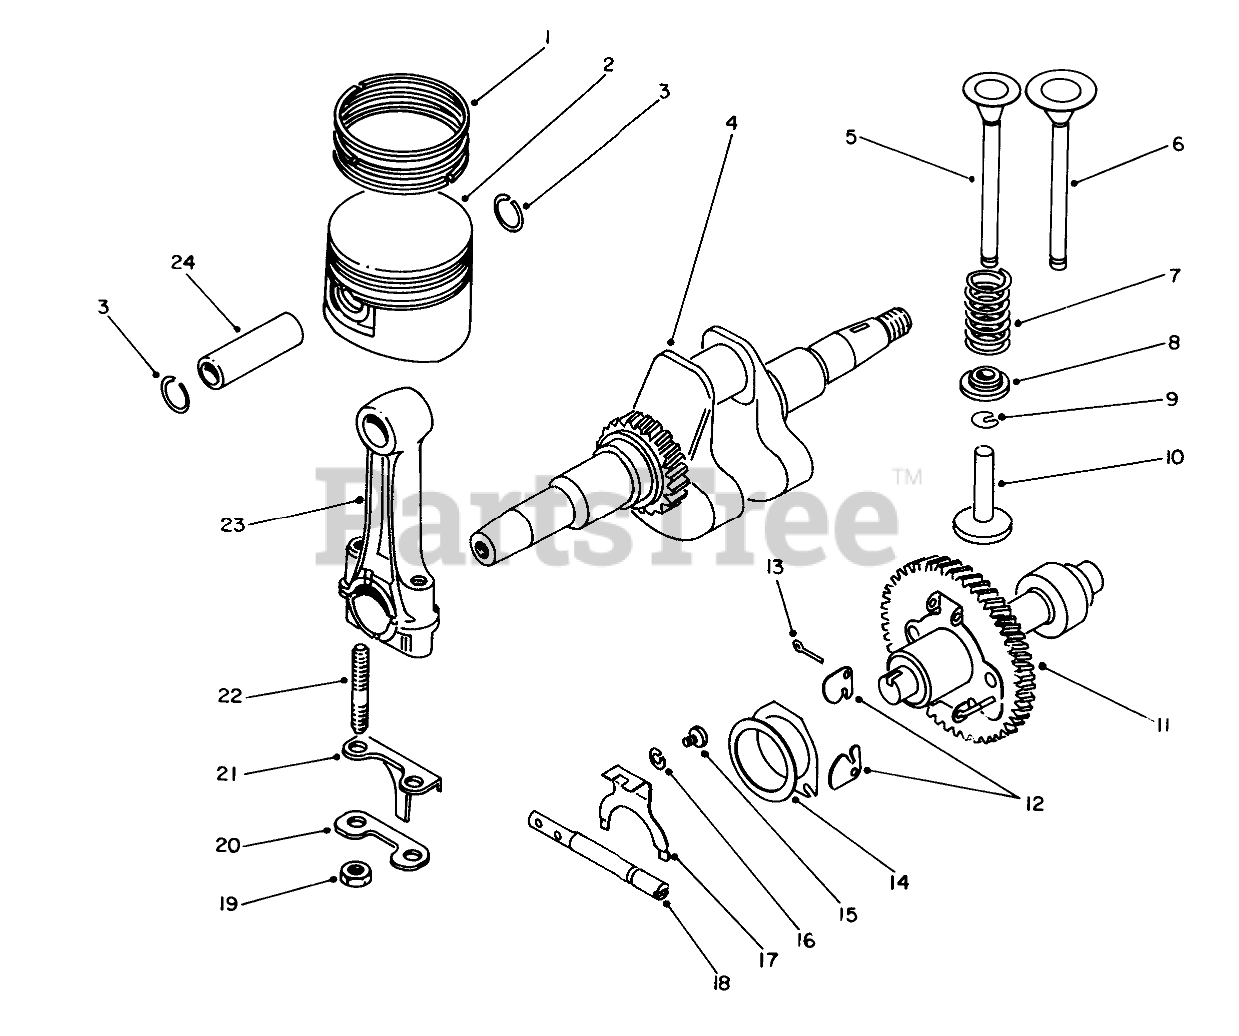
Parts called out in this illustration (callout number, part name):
1	Ring Set-Piston Std.
2	Piston Std
3	CIRCLIP
4	Crankshaft
5	EXHAUST VALVE
6	Valve-Intake
7	Spring-Valve
8	Retainer
9	Cotter
10	Tappet (L:40.26)
11	Cam Shaft
13	Cotter Pin
14	Spacer
15	SCREW
16	Washer
17	Plate-Shift
18	Shaft-Throttle Return
20	LOCK PLATE
21	Plate-Splash
22	Stud Bolt
23	Rod-Connecting (Incl.) Ref. #19-22)
24	PISTON PIN
